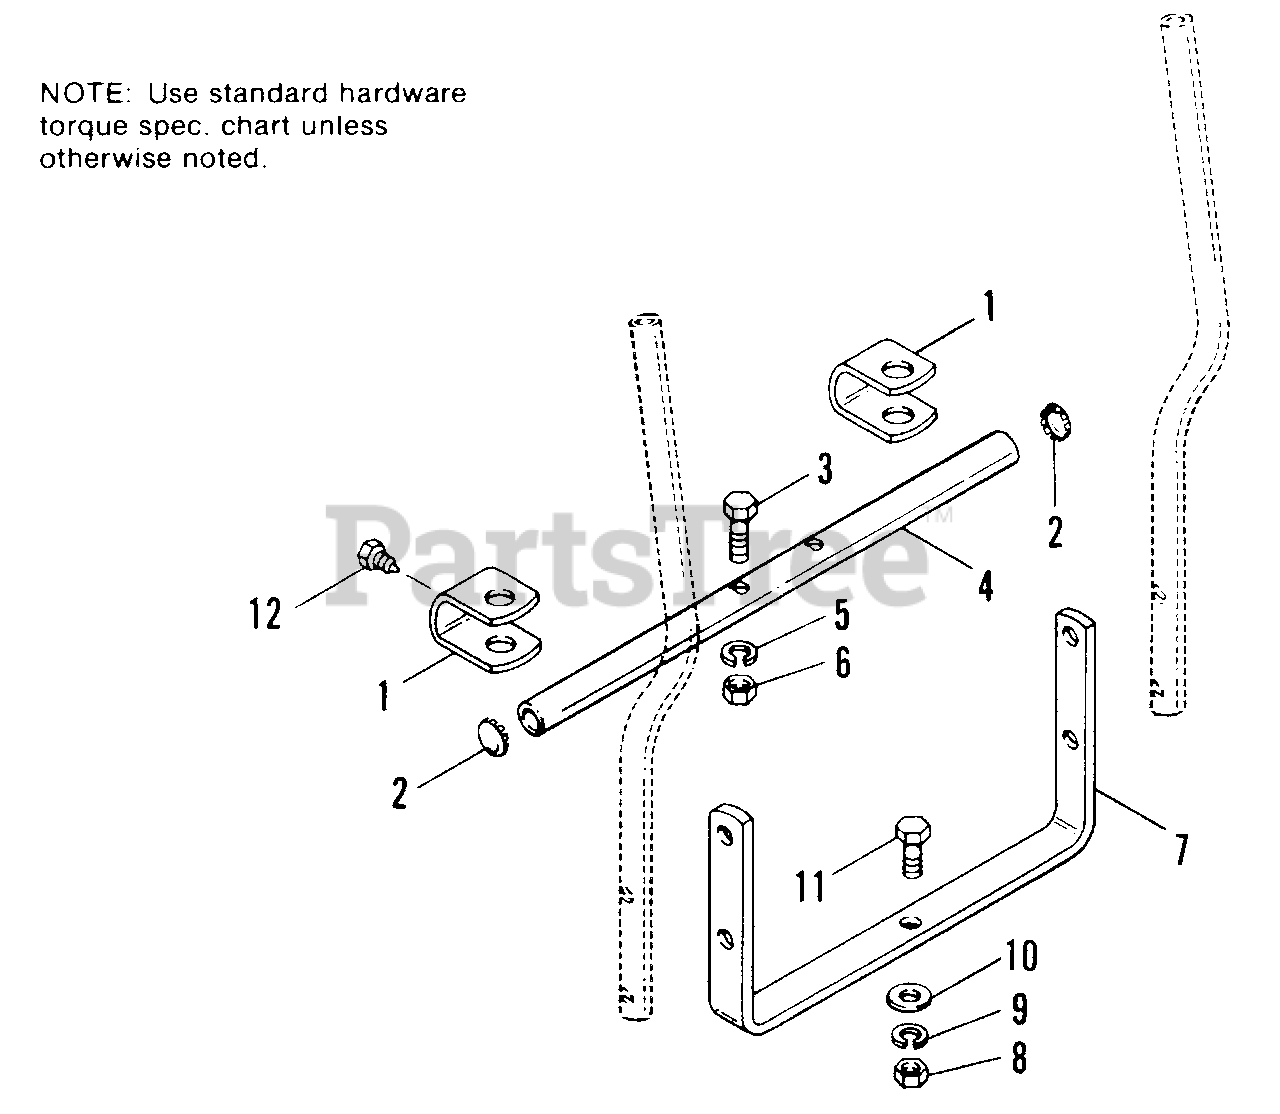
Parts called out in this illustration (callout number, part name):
2	BUTTON, Plug
3	CAPSCREW, Hex Hd., 5/16-18 x 1-1/2
4	TUBE, Rear
5	LOCKWASHER, 5/16
6	NUT, Hex, Full, 5/16-18
7	SUPPORT, Bracket
8	NUT, Hex, Full, 3/8-16
9	LOCKWASHER, 3/8
10	WASHER, Plain, 3/8
11	CAPSCREW, Hex Hd., 3/8-16 x 1
12	SCREW, Hex, Washer Hd., Taptite, 1/4-20 x 3/8
